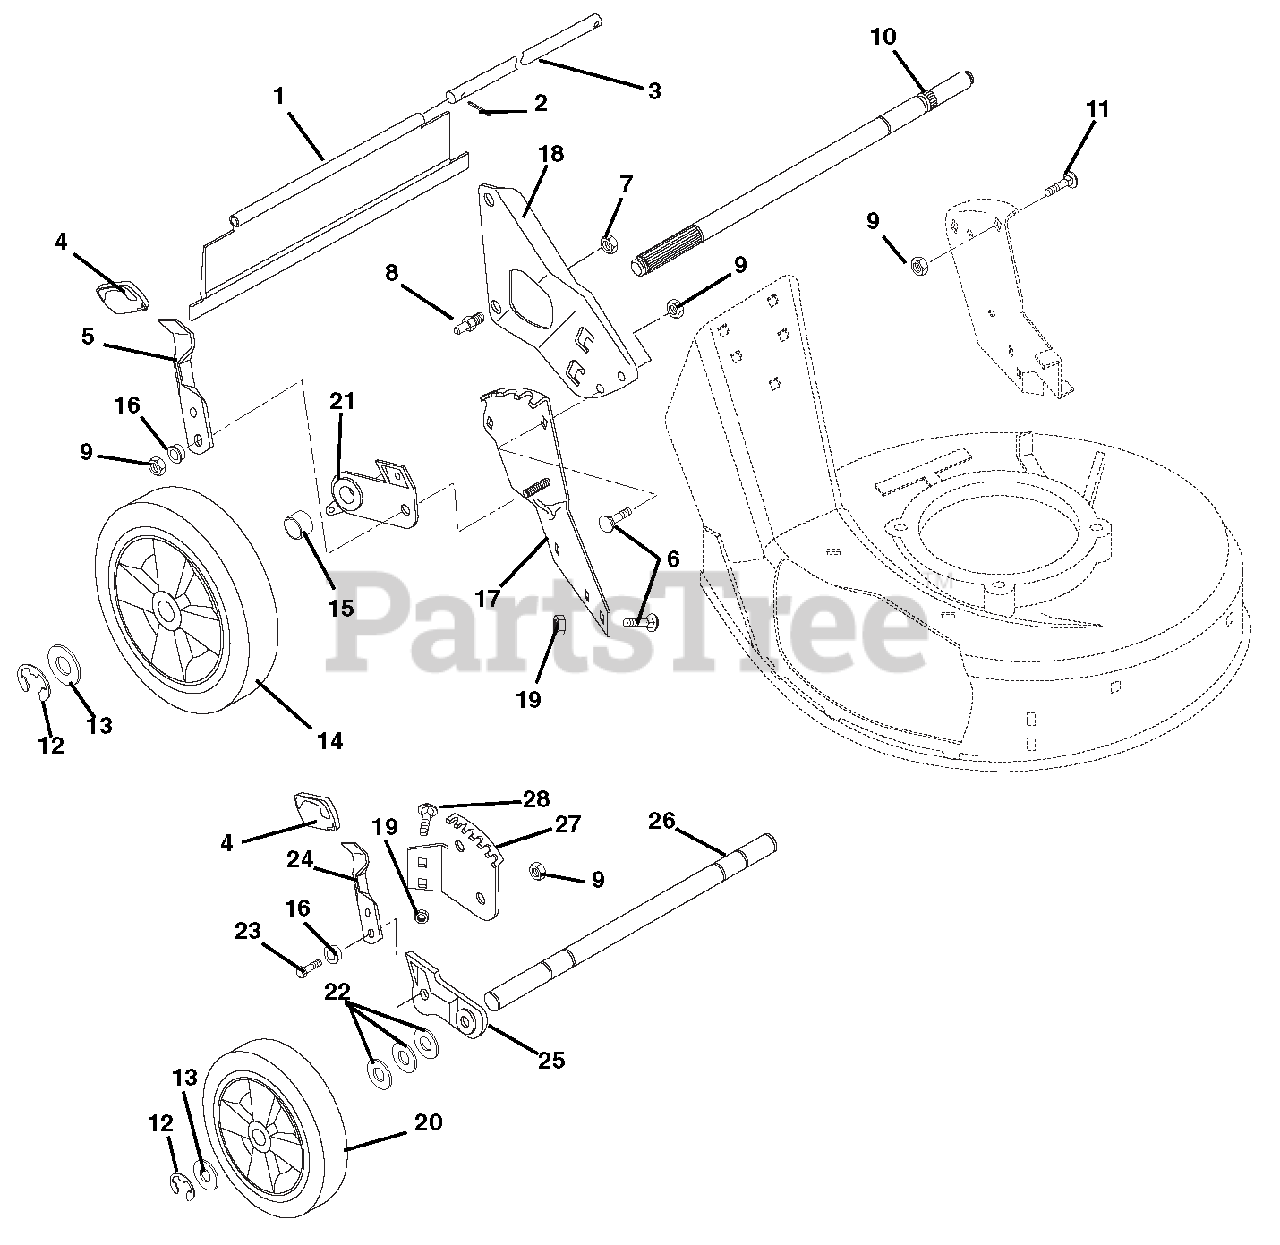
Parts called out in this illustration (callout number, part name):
1	REAR PROTECTIVE GUARD, S.P.
2	@PIN-CTR .06X.50 EXTPRSQCT YWZ
3	ROD
4	KNOB
5	LEVER, HEIGHT ADJUSTMENT
6	@BLT-RHDSSQNK .31-18X.62 G5YZ
7	@NUT-LK-CTR .38-16 YWZC
8	HANDLEBAR STUD
9	@NUT-LK-TOP-FLG .31-18 YWZC
10	REAR AXLE,5/8 DIA
11	BLT-RDHDSQNK .31-18X1.0 SHTYZ
12	RG-RTNG-EXT .500X.042 (E)
13	WSHR-FL-STL .505X.880X.072 YWZ
14	WHL, LH 10.50"
14	WHL, RH 10.50"
14	10 1/2 TIRE SKIN
15	SPACER TUBE, SELF PROPEL
16	BSHG-FLG .32X.500X.344X.880
17	QUADRANT, REAR LH
17	QUADRANT, REAR RH
18	RH HANDLEBAR MTG. BRKT
18	LH HANDLEBAR MTG. BRKT
19	@NUT-LK-TOP-FLG .31-18 YWZC
20	WHL 7.50" .50 BORE, 1.50 HUB
21	REAR BRACKET & BEARING ASSY LH
21	REAR BRACKET & BEARING ASSY RH
22	WSHR-FL-STL .52X.827X.062 YWZC
23	@BLT-HEX .31-18X1.00 GR5 YWZC
24	FRONT HEIGHT ADJUSTMENT LEVER
25	LEFT ADJUSTOR BRACKET ASSEMBLY
25	RIGHT ADJUSTOR BRACKET ASSEMBL
26	FRONT AXLE
27	FRONT QUADRANT, LH
27	FRONT QUADRANT, RH
28	@BLT-RDHDSQNK .31-18X.50 G5YZ
